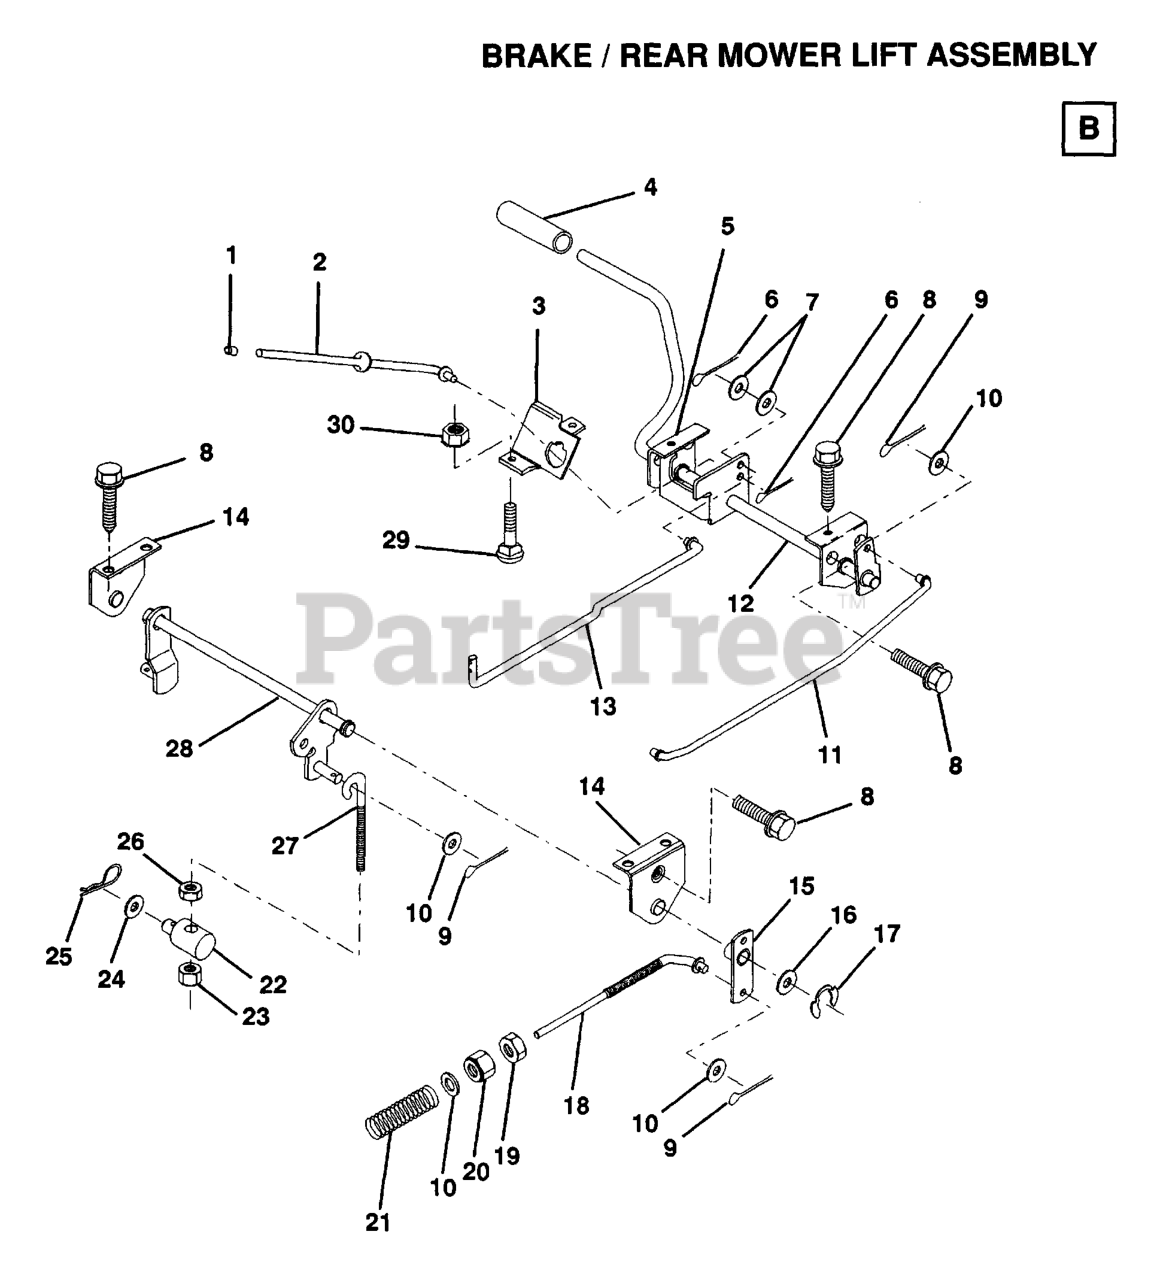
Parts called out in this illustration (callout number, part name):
1	PLUNGER CAP
2	ROD,PARK BRAKE
3	BRKT,PARK BRAKE
4	PEDAL COVER T
5	BRKT,CLU PEDAL LH
6	COTTER PIN
7	WASHER
8	Screw 5/16-18 x 1/2 Hex, Self Tapping 5/16-18 x 1/2
9	PIN COTTER
10	WASHER
11	ROD,FRT BRAKE
12	ASS'Y CLUTCH BRAK
13	ROD,CLUTCH
14	BRKT,LIFT SHAFT
15	BRAKE PIVOT ARM
17	Ring, Klip Truarc #5304-75
18	ROD REAR BRAKE
19	NUT
21	SPRING ROD LT
22	TRUNION LIFT
24	WASHER
25	COTTER PIN
26	LOCKNUT
27	LINK.MOWER.REAR
28	LIFT, REAR
29	BOLT.CARR.SQNK.5/16-18UNC.X3/4
30	LOCKNUT
